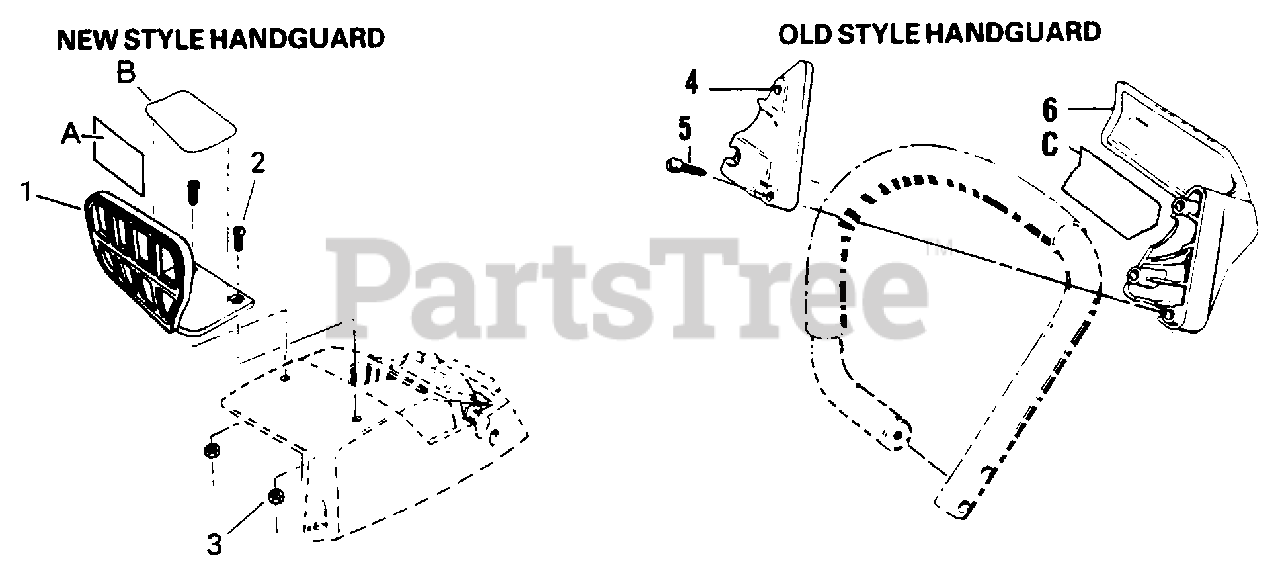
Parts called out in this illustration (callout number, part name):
1	Handguard
2	Screw - 10-24 x 1/2
3	Nut - #10-24
4	Cap - Handguard
5	Screw - #10 x 1 - Pan. Hd. - Handguard
6	Handguard
A	Decal - Kickback
A	Guide Bar Powerhead
A	Bow Guide Powerhead
B	Decal - Starting Instructions
C	Decal - Kickback Warning
C	Guide Bar Powerhead
C	Bow Guide Powerhead
